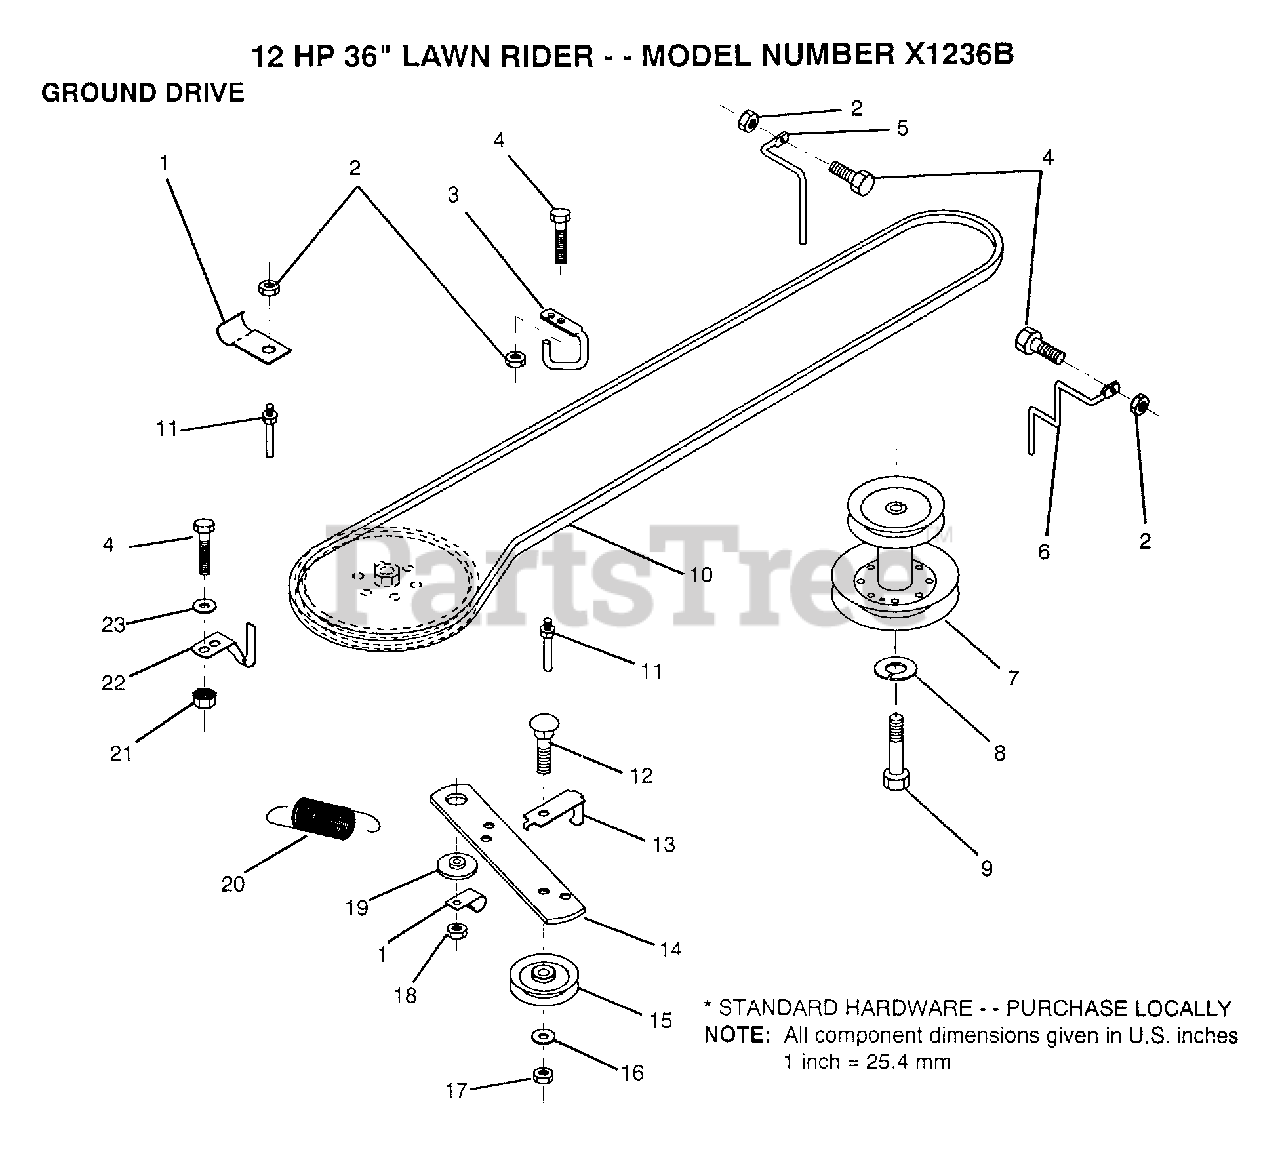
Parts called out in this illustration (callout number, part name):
1	"CLIP,INSULATOR"
3	"KEEPER,FRA DR BEL"
4	BOLT
5	KEEPER ENG BEL LH
6	KEEPER ENG DR RH
8	LOCKWASHER
9	BOLT
10	BELT
11	"KEEPER,DRIVE BELT"
12	BOLT
13	"KEEP,IDLER DR BEL"
16	WASHER
17	LOCKNUT
19	SPACER RETAINER
22	"KEEPER,DR BELT "
23	WASHER
